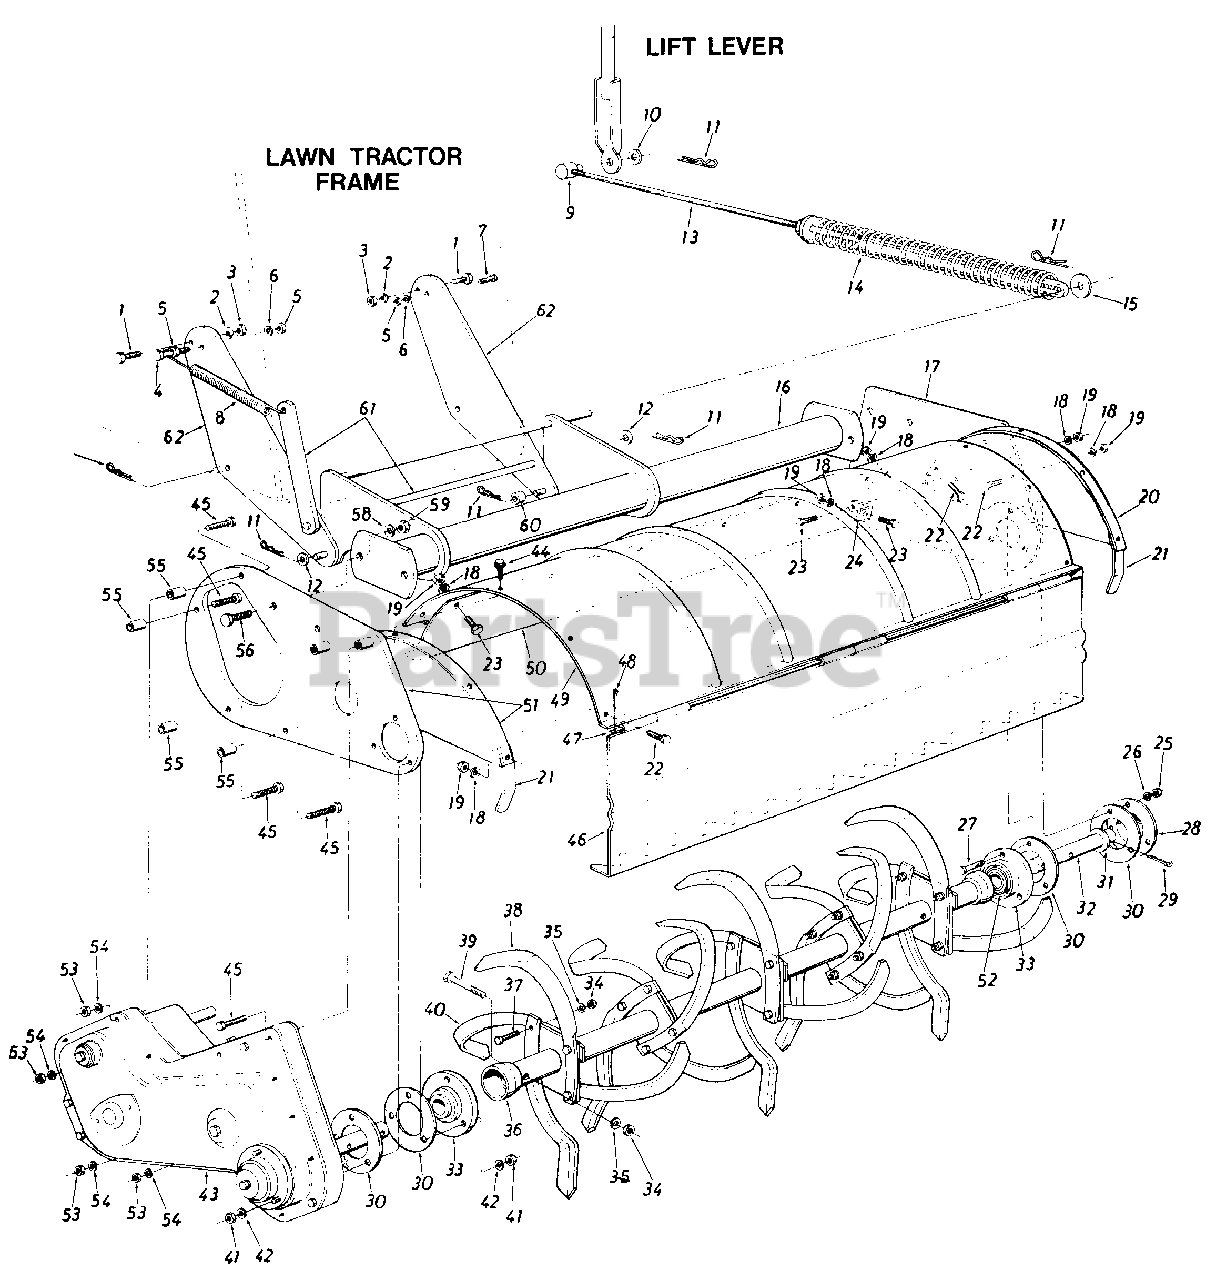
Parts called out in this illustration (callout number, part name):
1	Hex Bolt 3/8-24 x .88" Lg.*
2	L.-Wash. 3/8" I.D. Heavy Duty
3	Hex Nut 3/8-24 Thd.*
4	Hex Bolt 5/16-24 x 1.50" Lg.*
5	Hex Nut 5/16-24 Thd.*
6	L.-Wash. 5/16" I.D.*
7	Hex Bolt 5/16-24 x 1.00" Lg.*
8	Extension Spring .56" O.D. x 7.75" Lg.
9	Adjustment Ferrule 1/2-13 Thd.
10	Fl.-Wash. .640" I.D. x 1.24" O.D. x.060
11	Intern. Cotter Pin 1/2" Dia.
12	Fl.-Wash. .510" I.D. x 1.0" O.D. x .060
13	Lift Rod Ass'y. 39.0" Lg.
14	Compression Spring 1.50" O.D. x 15.0" Lg.
15	Fl.-Wash. .51" I.D. x 1.50" O.D. x .075
16	Pivot Bracket Assembly
19	Hex Nut 5/16-24 Thd.*
23	Hex Bolt 5/16-24 x .62" Lg. *
24	Chute Pivot Bracket
25	Hex Cent. L-Nut 5/16-18 0 Thd.
26	L.-Wash. 5/16" I.D.*
27	Hex Bolt 5/16-18 x 1.0" Lg. (Grade 5)
30	Gasket for Brg. Housing
31	Fl.-Wash. 1.25" I.D. x 2.00" O.D. x .60
32	Tine Shaft R.D. 1.25" Dia. x 6.25" Lg.
33	Bearing Housing w/Bearing
34	Hex Nut 3/8-24 Thd.*
35	L.-Wash. 3/8" I.D. Heavy Duty
38	Tine 14" x 5/16"
39	Hex Bolt 3/8-24 x 2.25" Lg.*
40	Tine 14" x 5/16"
41	Hex Cent. L.-Nut 5/16-18Thd.
42	L. Wash. 5/16" I.D.*
43	Chain Case Ass'y. Comp.
44	Hex Wash. TT Tap. Scr. 5/16-18 x .62" Lg.
45	Hex Bolt 1/4-20 x 2.75" Lg.*
48	Cotter Pin 1/8" Dia. x 1.00" Lg. *
53	Hex Nut 1/4-20 Thd.*
54	L.-Wash. 1/4" I.D.*
55	Spacer.28" I.D. x .62" O.D. x .90" Lg.
56	Hex Bolt 1/2-13 x 1.00" Lg.*
58	L.-Wash. 1/2" I.D.*
59	Hex Nut 1/2-13 Thd.*
60	Spacer.50" I.D. x 1.00" O.D. x .50" Lg.
61	Idler Bracket Support Arm Ass'y
62	Pivot Bracket SunDort
